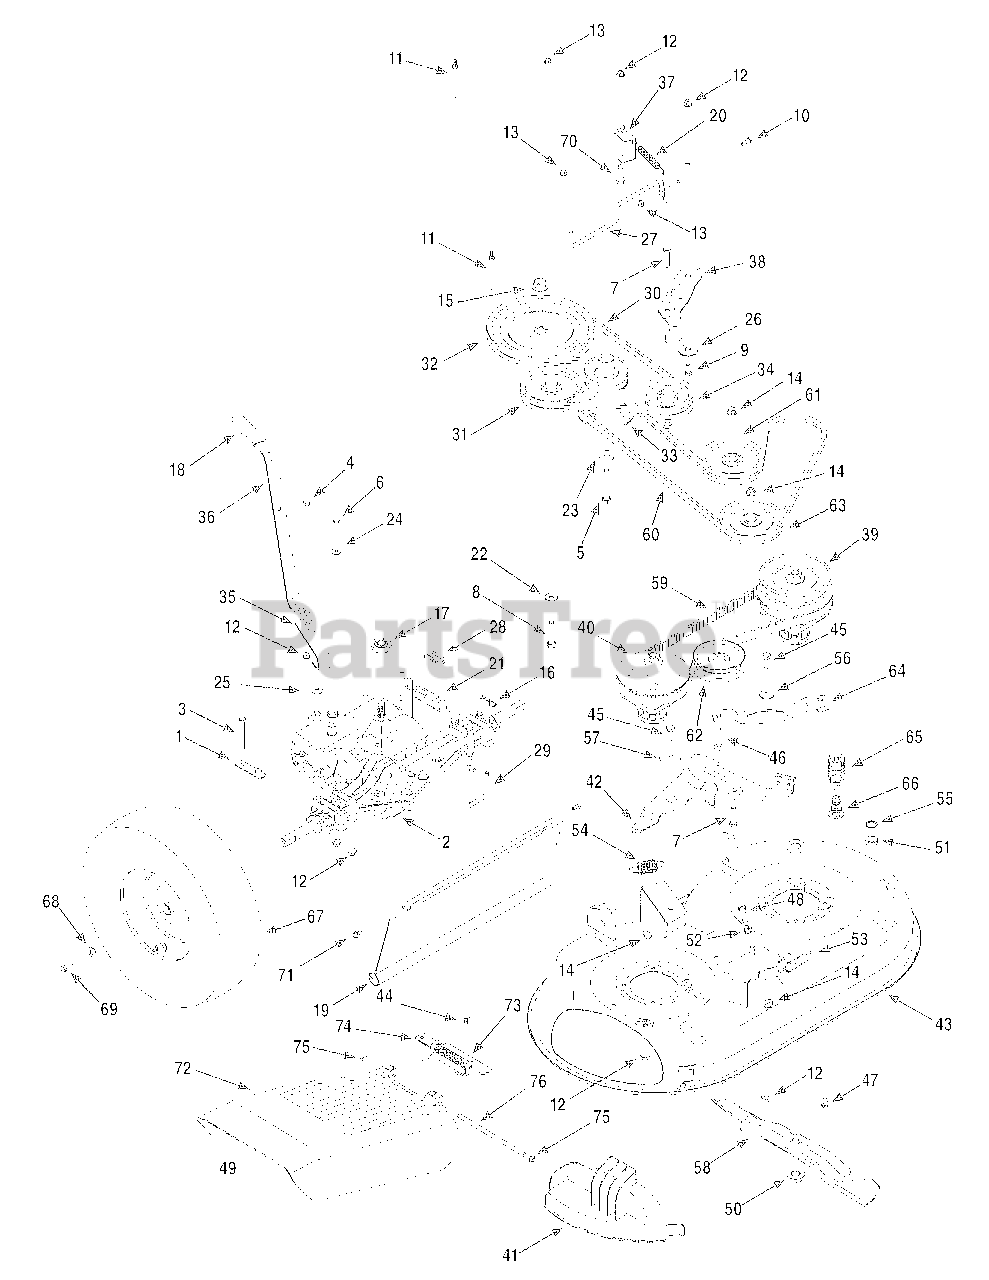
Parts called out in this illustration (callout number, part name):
1	Transaxle Bracket Mount
2	Transmission 4-Speed
3	Screw, HH Cap: 5/16-18 x 2.75"
4	Screw, HH Cap: 5/16-18 x 1.00"
5	Screw, HH Cap: 7/16-20 x 2.75"
6	Screw, HH Cap: 1/4-28 x .625"
7	Screw, HH Cap: 3/8-16 x 1.50"
8	Screw, HH Cap: 3/8-16 x 1.75"
9	Screw, HH Cap: 5/16-18 x .75"
10	Screw, HH Cap: 1/4-20 x .75"
11	Belt Keeper
12	Nut, Flange Lock: 5/16-18
13	Nut, Flange Lock: 1/4-20
14	Nut, Flange Lock: 3/8-16
15	Nut, Flange: 9/16-18
16	Hairpin Clip: 092" x 1.64" Long
17	Pulley Hub
19	Trailing Shield
20	Extension Spring
21	Extension Spring
22	Washer, Spring: .401" x .870" x .063"
23	Washer, Flat: 450" x 1.250" x .164"
24	Washer, Bell
25	Washer, Flat: .39" x .87" x .06"
26	Spacer, Shoulder: .50" x .1475"
27	Belt Keeper Rod
28	Loop Link Coupling
29	Trans Mount Rod
30	Belt, V Type
31	Idler Pulley: 4.25" Dia.
32	Flat Sheave 7.75"
33	Engine Pulley 3.20" x 4.35" Dia.
34	Idler Pulley 3.50" Dia.
35	Shift Rod, Lower
36	Shift Rod, Upper
37	Belt Keeper
38	Wheel Drive idler Bracket
39	Drive Spindle Assembly
40	Spacer Spindle Assembly
41	Mulch Plug
42	Idler Arm Assembly
43	Deck Assembly 33-inch
44	Bolt, Carriage: 5/16-18 x .75"
45	Screw, HH Cap: 3/8-16 x 1.00"
46	Screw, Carriage: 3/8-16 x 1.75"
47	Screw, LD: 5/16-18 x .750"
48	Screw, HH Cap: 3/8-16 x 2.00"
49	Chute Deflector Assy (includes ref. 72-76)
50	Nut, Flange: 5/8-18
51	Nut, Hex
52	Nut, Hex 3/8-16
53	Extension Spring: Timing Belt Tension
54	Extension Spring: Deck Brake
55	Washer, Lock
56	Spacer, Shoulder: .625" x .169"
57	Spacer, Shoulder: .884" x .190"
58	Blade: 17.9"
59	Belt, Timing
60	Belt, V Type
61	Idler Pulley 4.25"
62	Idler Pulley 3.50"
63	Idler Pulley V-Type 5.0"
64	Idler Timing Bracket
65	Water Nozzle Adapter
66	Water Nozzle
67	Wheel 16 x 4 x 8
68	Washer, Bell: .340" x .872" x .060"
69	Screw, HH Cap: 5/16-24 x .75"
70	Screw, TT: 3/8-16 x 1.25"
71	Screw, HL: 1/4-15 x .50"
72	Chute Deflector, 33" SD Deck
73	Deflector Hinge Bracket
74	Deflector Torsion Spring
75	Push Cap
76	Deflector Pin
